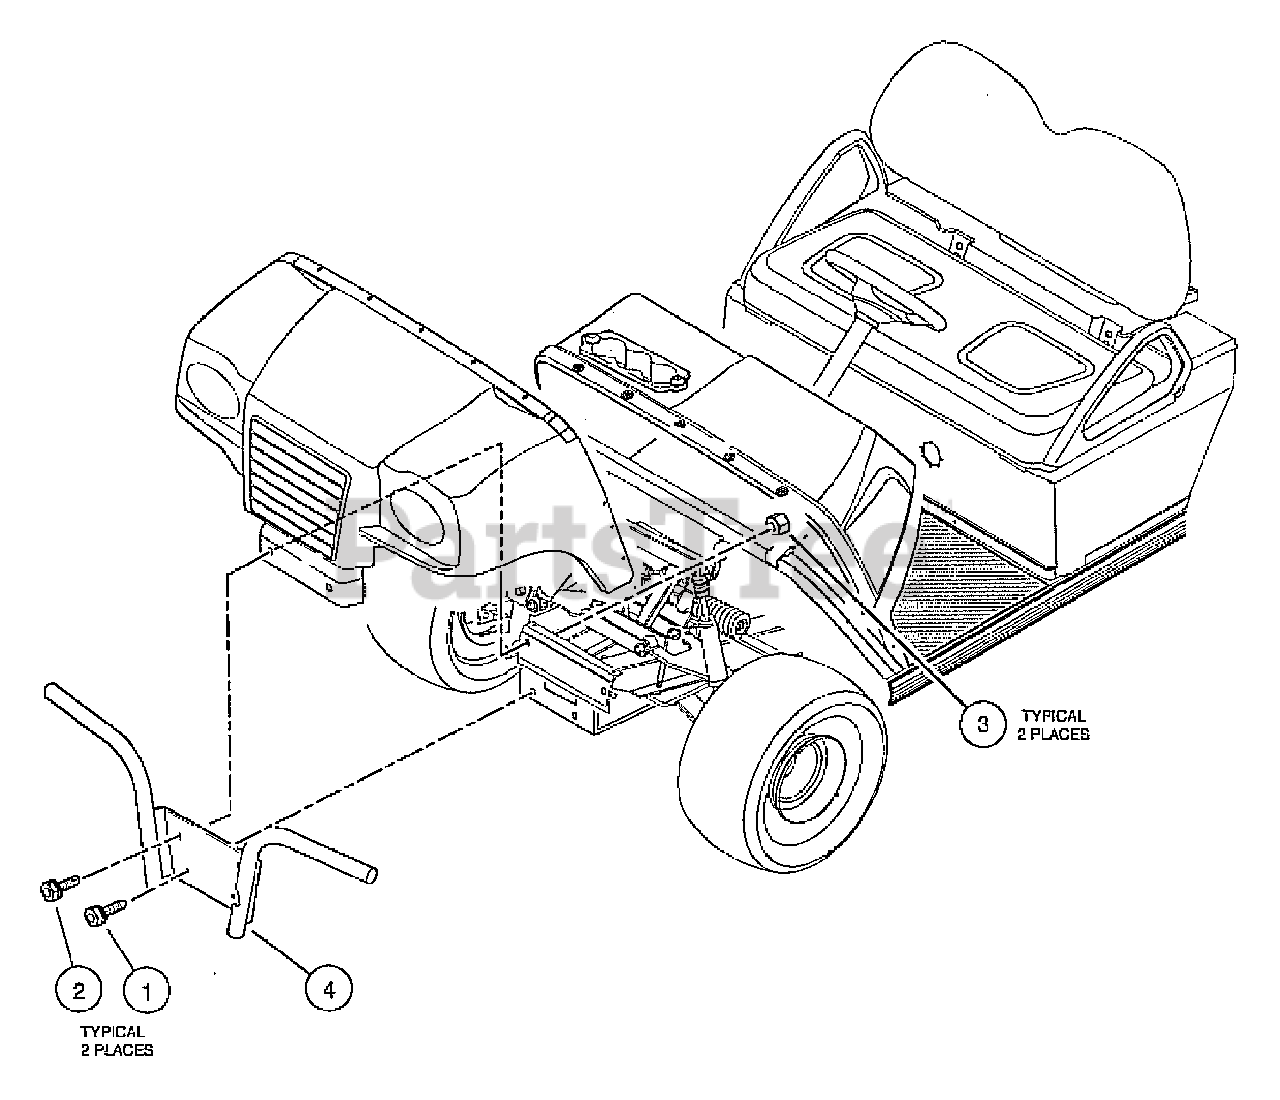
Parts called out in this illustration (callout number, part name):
1	Screw, MB X 1.25 X 30 TO, Blk
2	Bolt, Flange Head, M8-1.25 X 40
3	Lock Nut, Flg M8 X 1.25 Nylon
4	Guard, Brush
